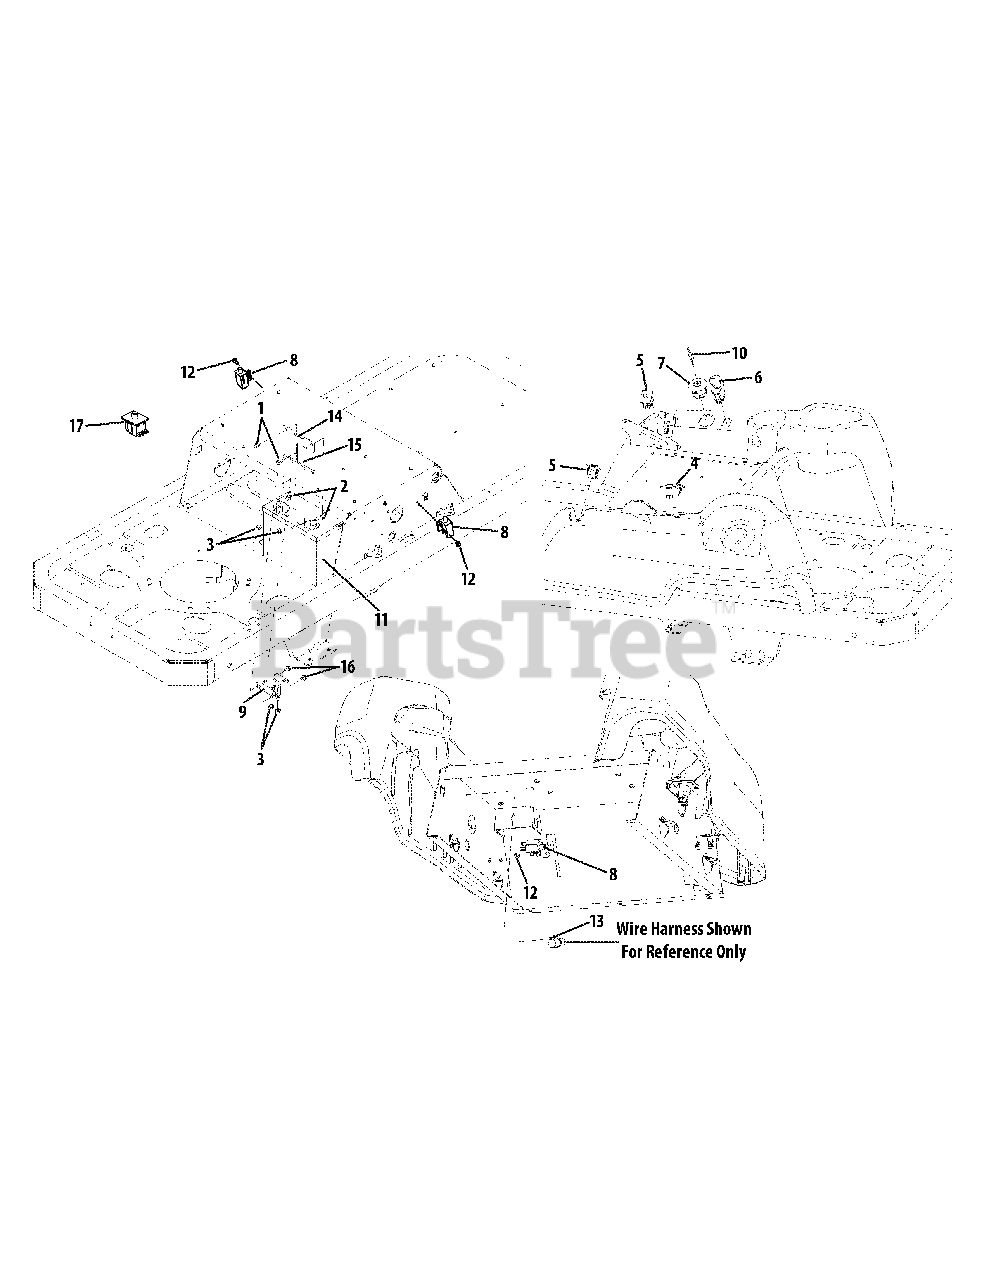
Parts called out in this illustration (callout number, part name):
1	Hex Screw, 1/4-20 x .5
2	Hex Screw, 1/4-20 x .75
3	Hex Nut, 1/4-20
5	Double Pole - Neutral Switch
6	PTO Switch
7	Ignition Switch
8	Interlock Switch
9	Solenoid
10	Key
11	Battery, 235 CCA
12	Shoulder Screw, #10-32 x .500
13	Cable Tie
14	Batter Hold-down
15	Trim Strip
16	Hex Screw, 1/4-20 x .375
17	Seat Switch
